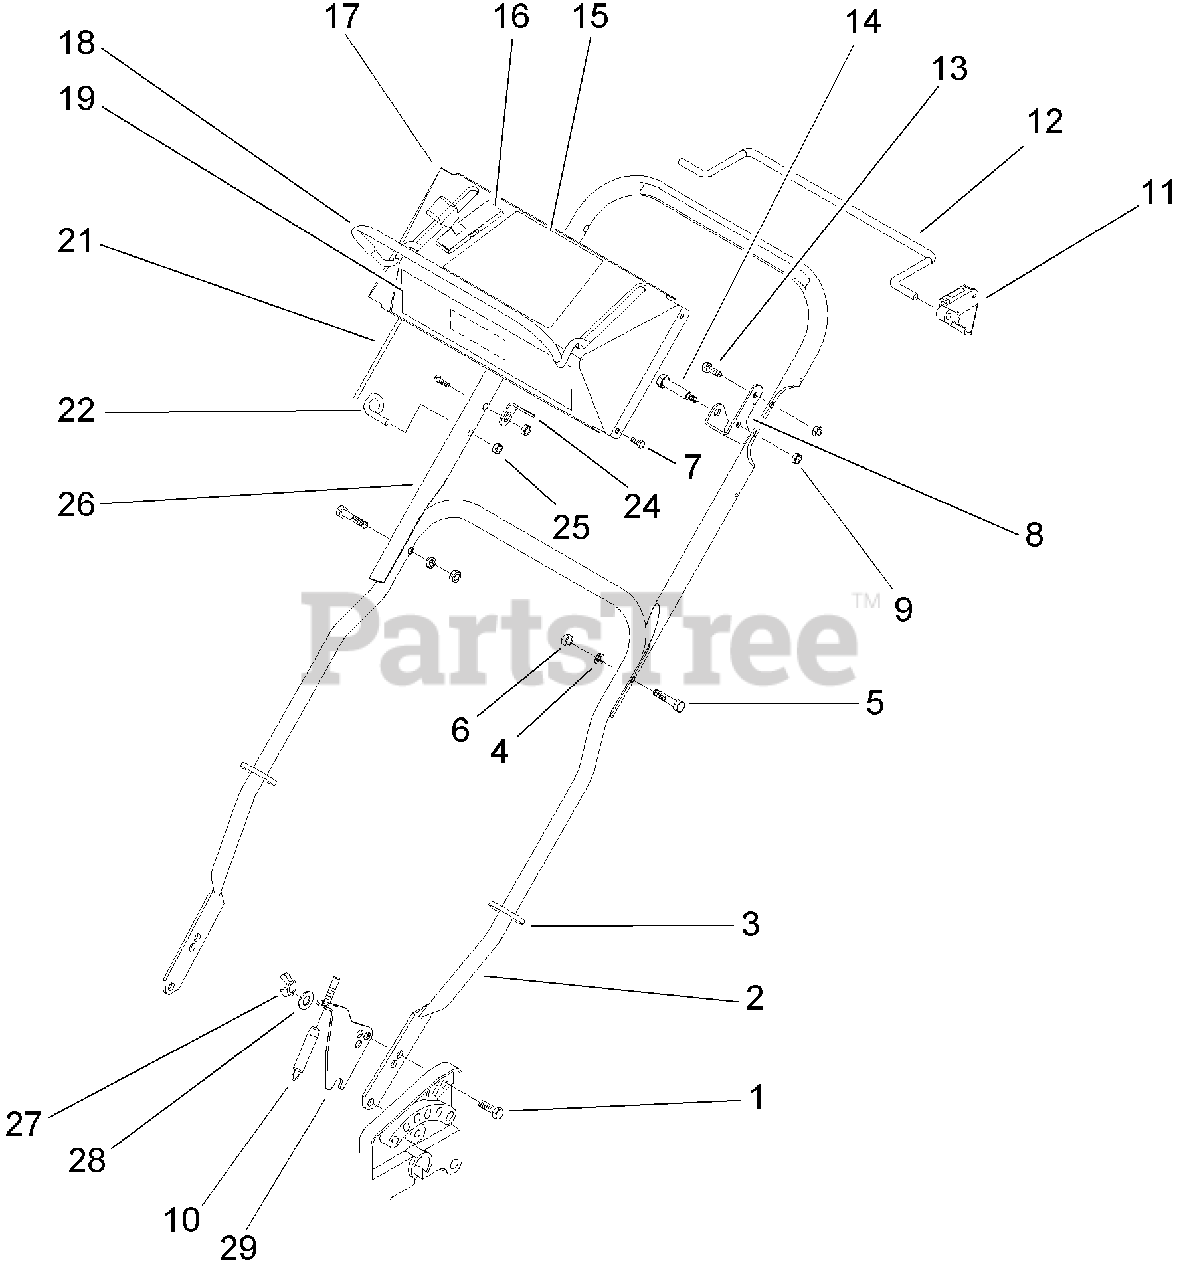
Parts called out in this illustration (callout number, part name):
1	SCREW-CARR
2	HANDLE-LOWER
3	STRAP-TIE
4	WASHER-CURVED
5	SCREW-HH
6	NUT-LOCK, NI
7	SCREW-THREAD CUT
8	BRACKET-STOP, BAIL
9	NUT-LOCK, NI
10	CABLE-TRACTION
11	STOP-PIVOT
12	BAIL-CONTROL
13	SCREW-HH
15	DECAL-CONTROL PANEL
16	CABLE-GROUND SPEED
17	PANEL-CONTROL
18	BAIL-ENGINE CONTROL
19	DECAL-PANEL, FRONT
21	BRAKE CABLE ASM
22	GUIDE-ROPE
24	BRACKET-ANCHOR, CABLE
25	NUT-LOCK, NI
26	HANDLE-UPPER
27	NUT-LOCK, NI
28	WASHER-FLAT
29	BRACKET-CABLE, TRACTION
